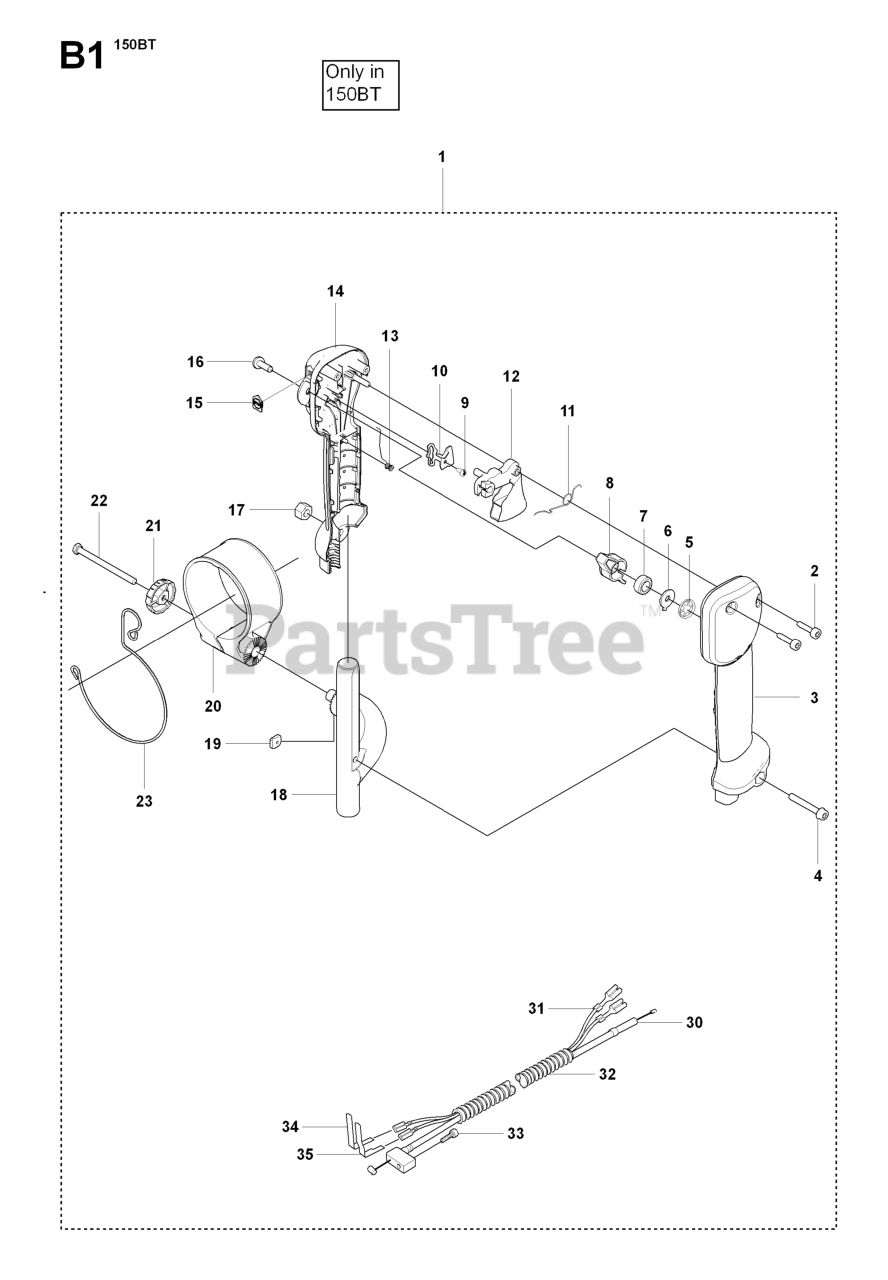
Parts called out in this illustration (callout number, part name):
1	HANDLE ASSY 150BT
3	HANDLE HALF (R)
4	SCREW
7	SPRING RUBBER
8	LEVER STOP
12	TRIGGER 848L5W34C0
14	HANDLE HALF (L)
16	SHAFT PIVOT
18	HOLDER, HANDLE
20	HOLDER TH
21	KNOB
30	CABLE COMP
31	RP CORD
34	CONTACT SPRING
35	CONTACT SPRING
